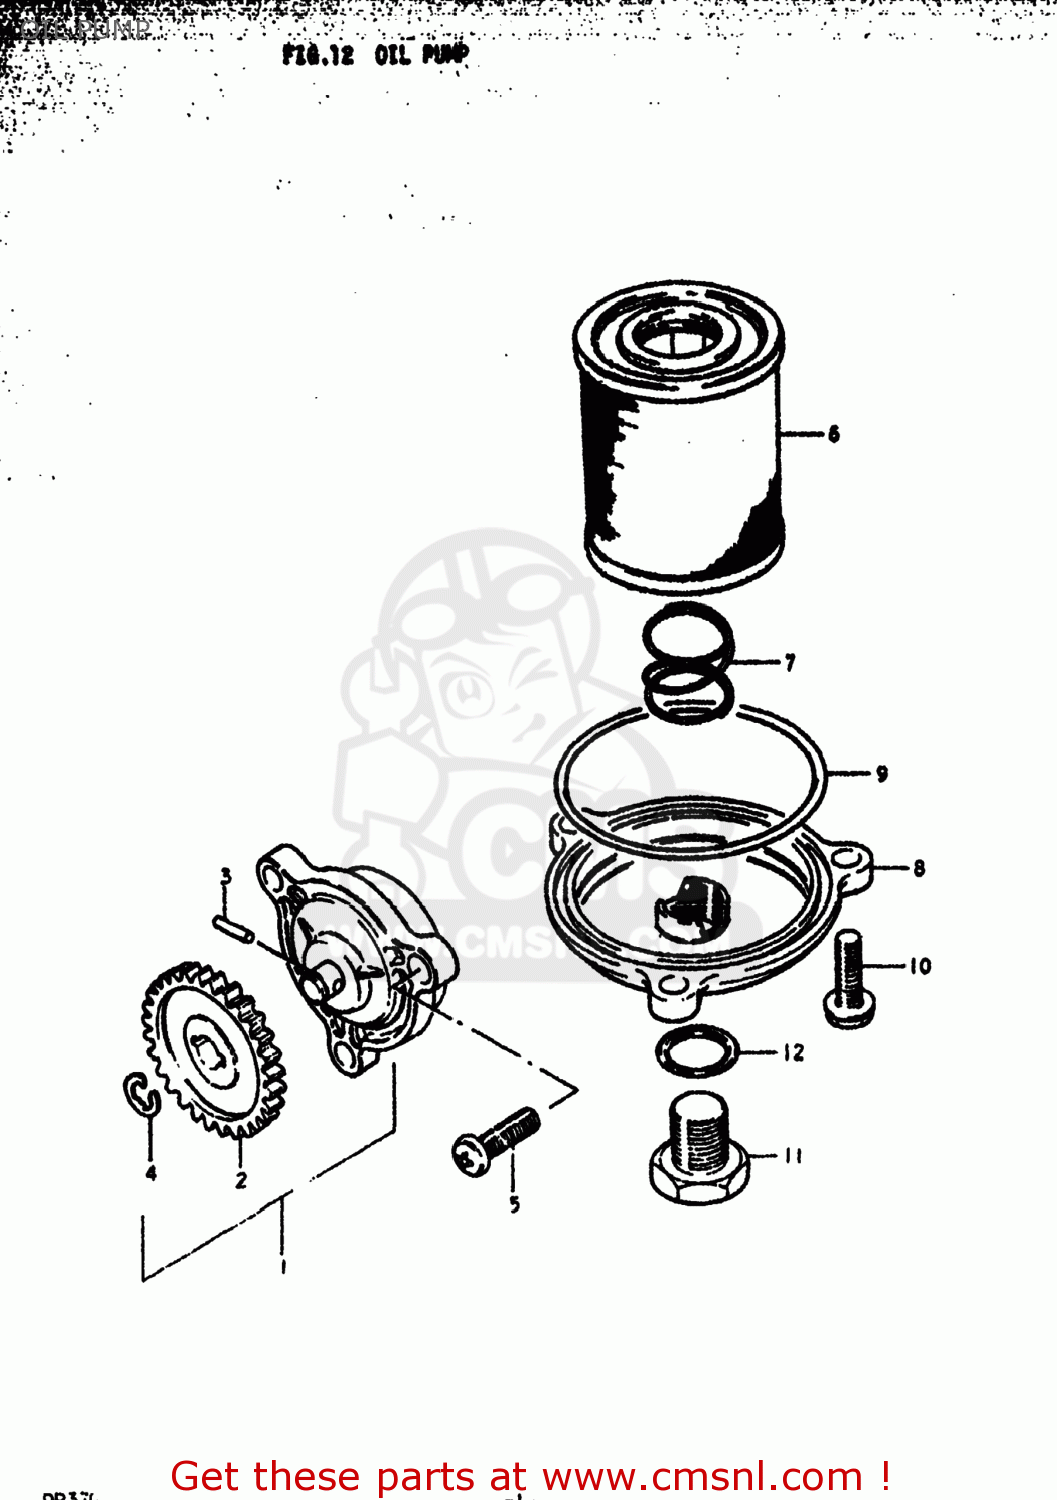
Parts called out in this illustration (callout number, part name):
1	PUMP ASSEMBLY,ENGINE OIL
2	GEAR,OIL PUMP DRIVEN
3	PIN(2.5X11.8)
4	E RING 6MM
5	SCREW
6	STRAINER,OIL
7	SPRING
8	CAP,ENGINE OIL STRAINER
9	O RING(D:2.4,ID:62.6)
10	BOLT,REAR
11	PLUG
12	GASKET(14X19.2X2) (NAS)
